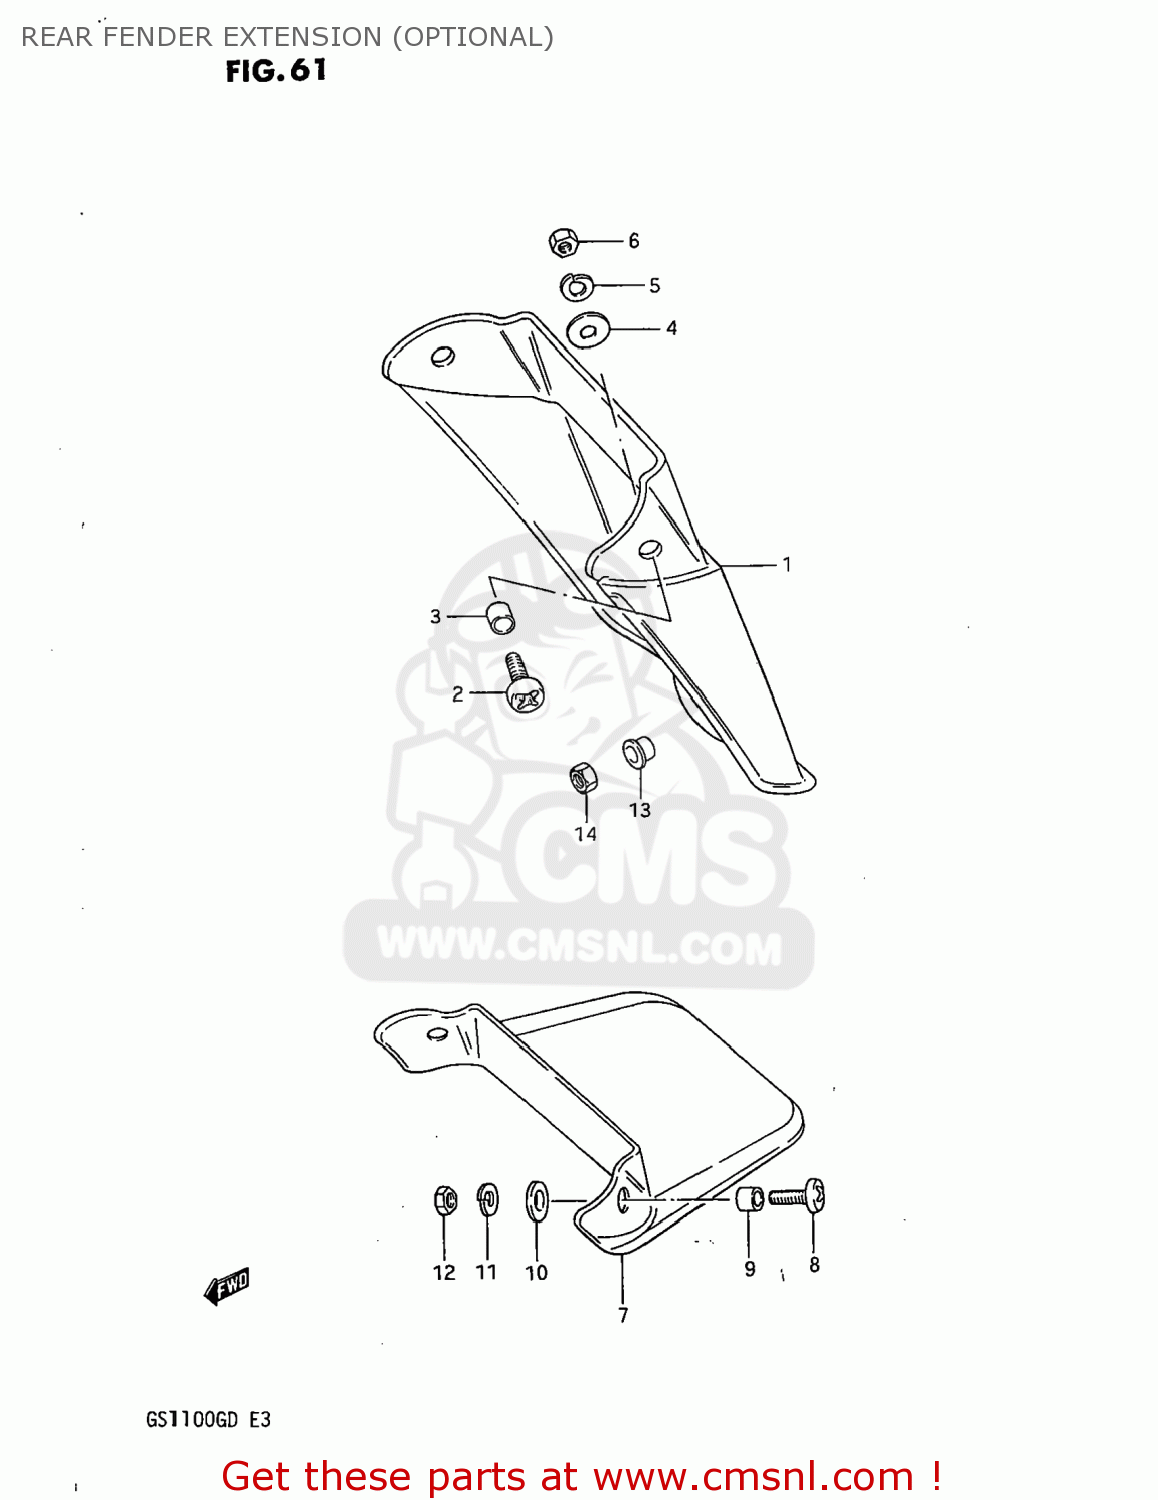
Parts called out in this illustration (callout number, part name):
1	EXTENSION,REAR FENDER
2	SCREW (6X15)
3	SPACER(6.2X8.3X5.7)
4	WASHER(6.5X18X1)
5	LOCK WASHER
6	NUT
7	EXTENSION,REAR FENDER
8	SCREW (6X15)
9	SPACER(6.2X8.3X5.7)
10	WASHER(6.5X18X1)
11	LOCK WASHER
12	NUT
13	SPACER
14	NUT
